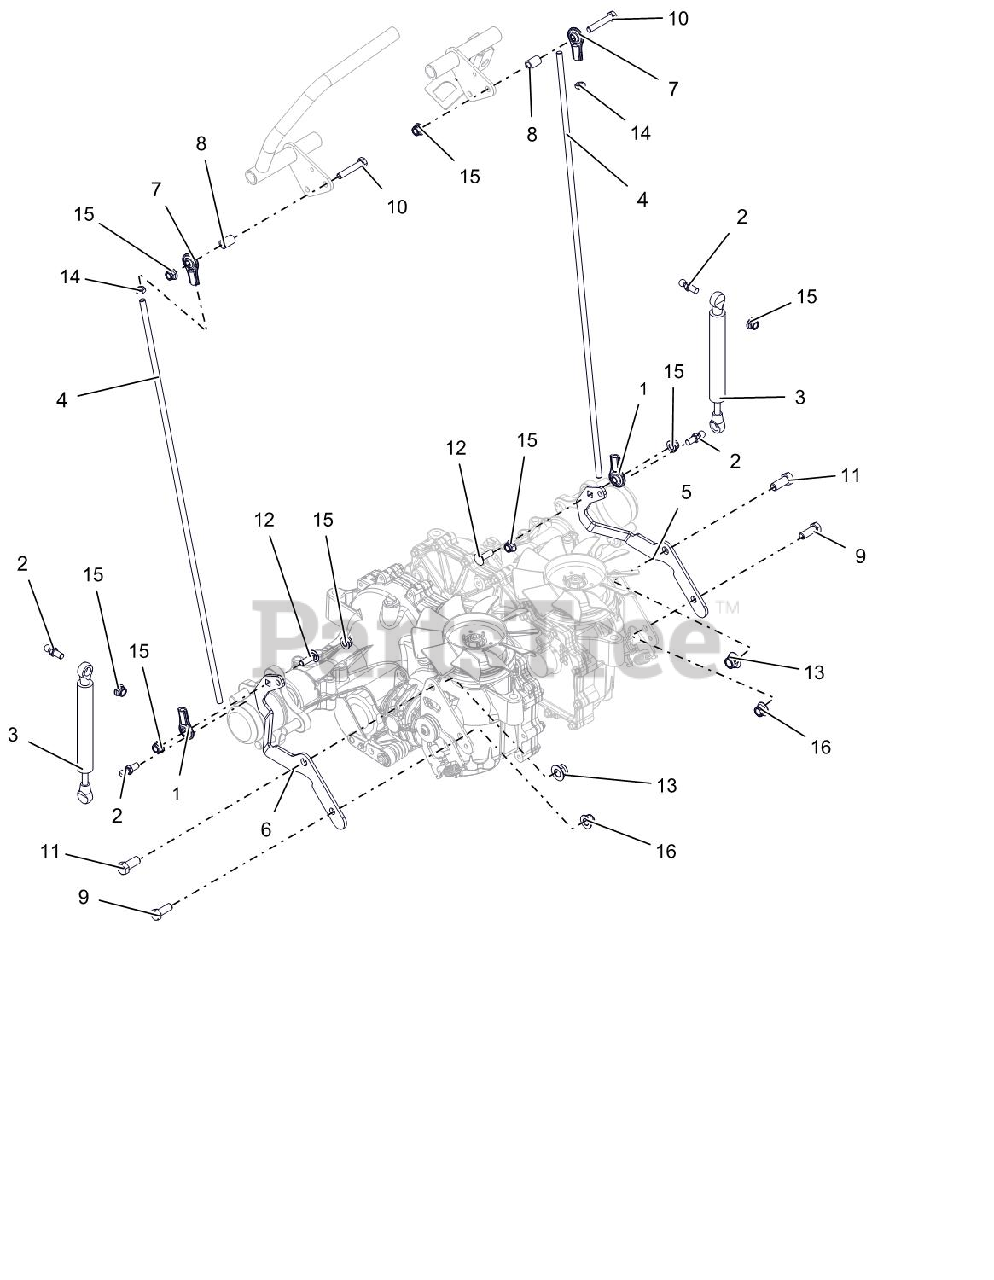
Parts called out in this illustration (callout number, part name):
1	ALIGNABALL, 5/16 RH THREAD
2	STUD- BALL
3	DAMPER, CONTROL
4	ROD, STEERING
5	BRKT, LH TRANS CONTROL
6	BRKT, RH TRANS CONTROL
7	ALIGNABALL, 5/16 LH THREAD
8	BSHG-SLV .328X.50X.75
9	@BLT-HEX .38-16X1.00 GR5 YWZC
10	@BLT-HEX .31-18X1.75 GR5 YWZC
11	@BLT-HEX .44-14X1.00 GR5 YWZC
12	@BLT-RDHDSQNK .31-18X1.00 G5YZ
13	@NUT-LK-NYL-FLG .44-14 YWZC
14	NUT-JAM LH .31-24 YWZC
15	@NUT-LK-NYL-FLG .31-18 YWZC
16	@NUT-LK-NYL-FLG .38-16 YWZC
